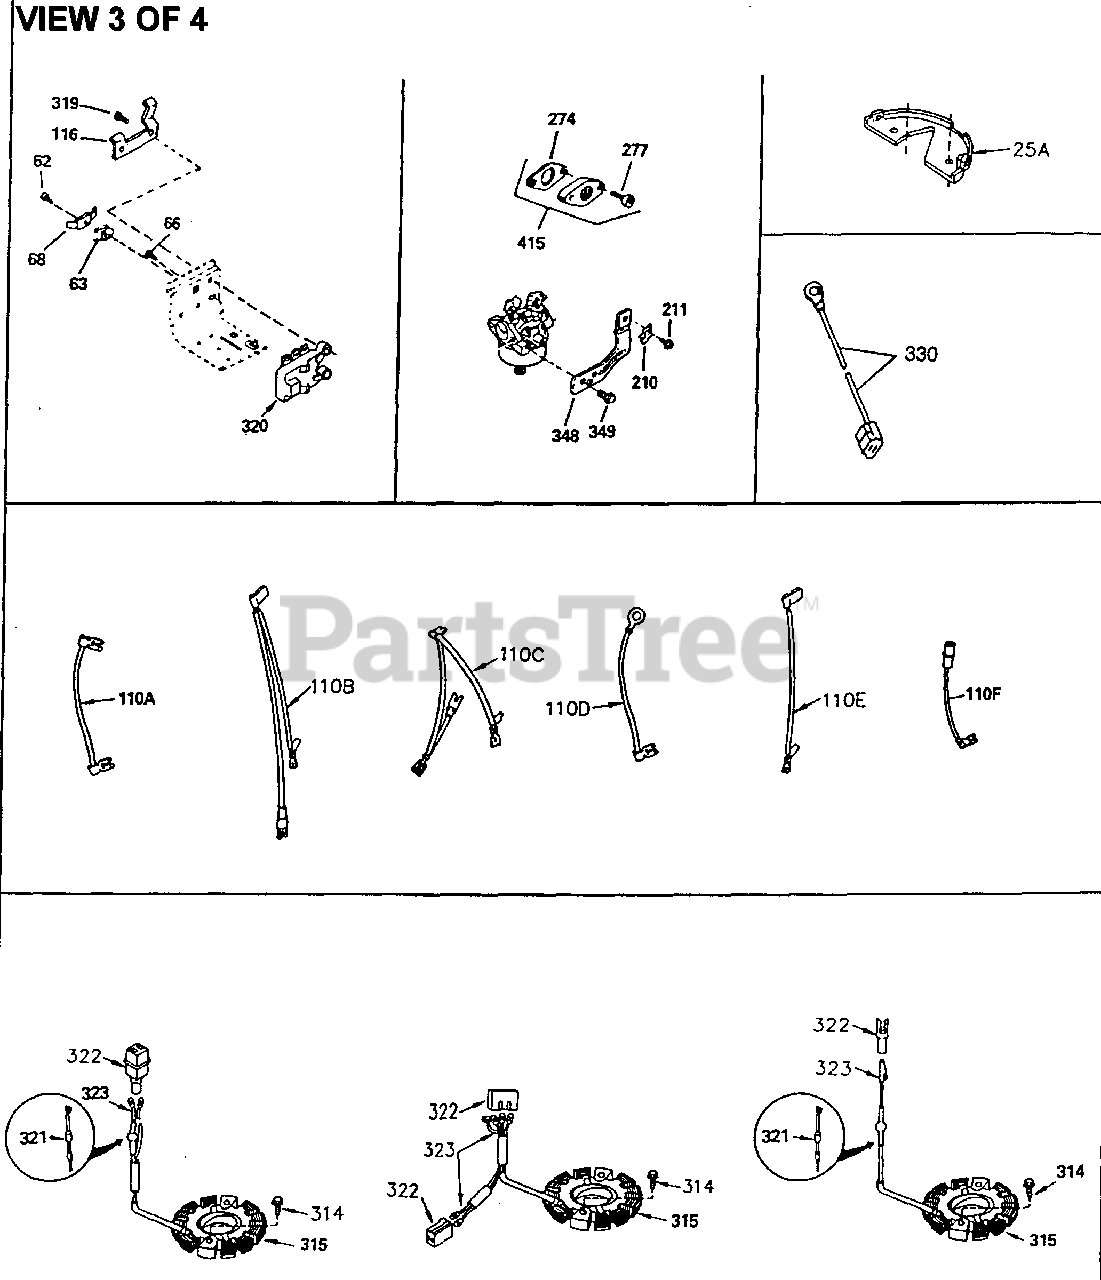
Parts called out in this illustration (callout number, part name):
64	Screw, T-30, 1/4-20 x 1/2"
210	Conduit Clip
211	Screw, 10-32 x 3/8"
251A	Nut & Lock Washer, 1/4-20
314	Screw, 1/4-20 x 3/4"
315	Alternator Coil Incl. 322, 322A & 323
319	Screw, 10-24 x 3/8"
320	Regulator (7 Amp D.C.)
322	Connector Body
322A	Connector Body
323	Terminal
